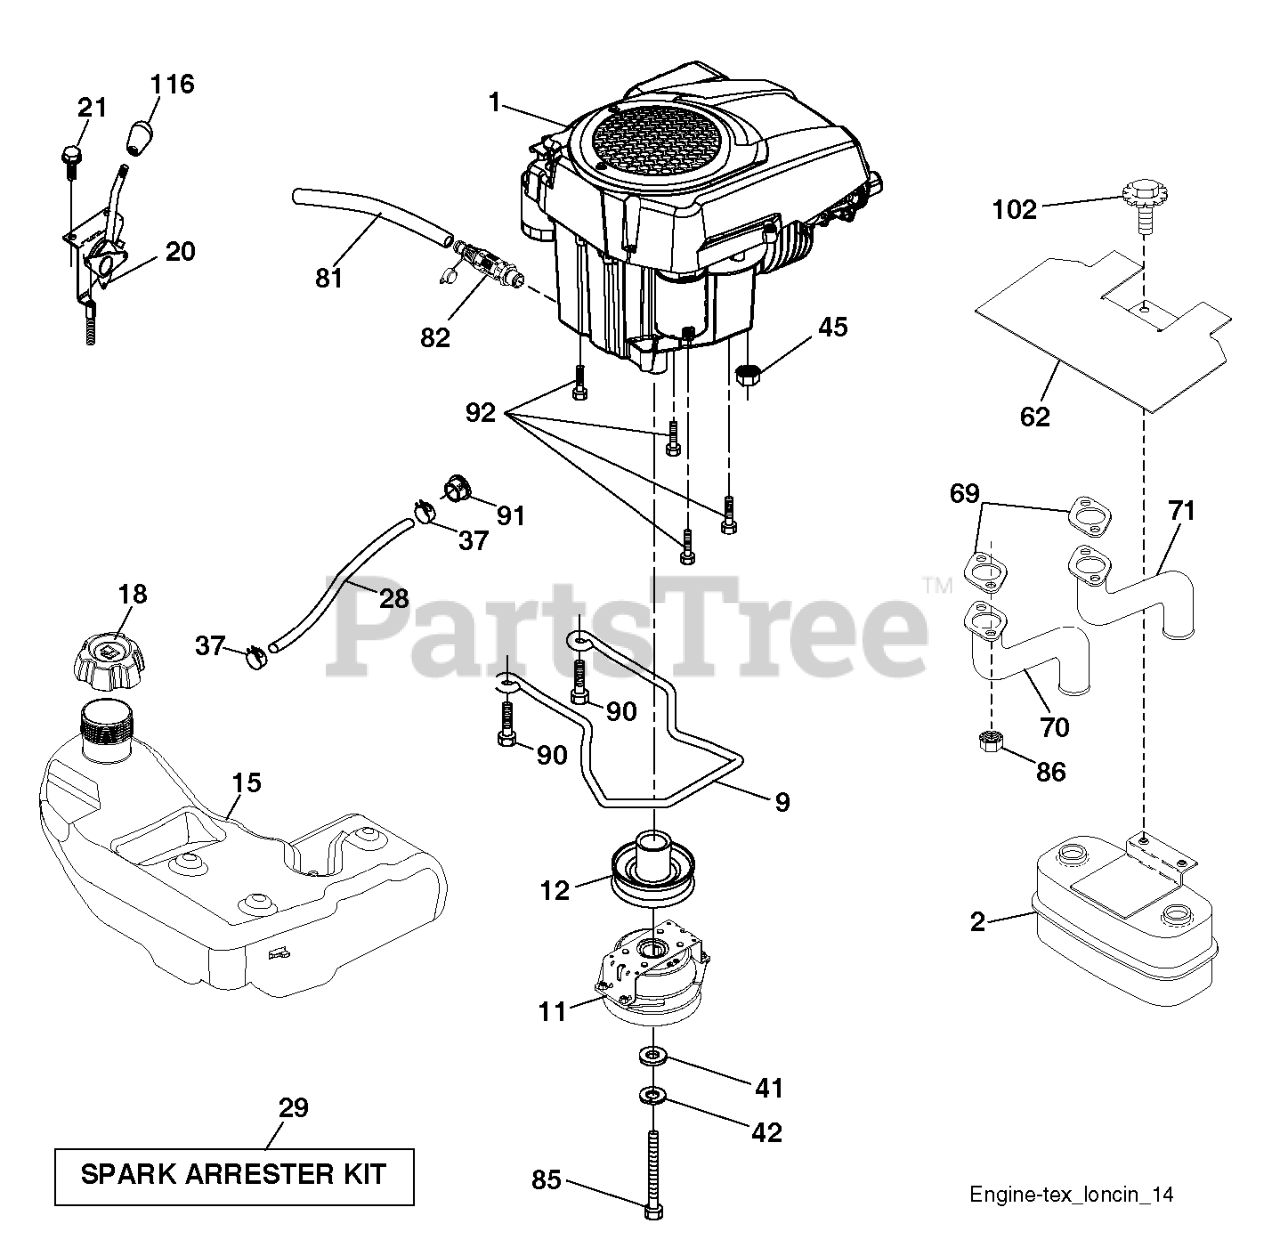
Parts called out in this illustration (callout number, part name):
2	MUFFLER.ASM.TWIN.MNTG.BRACKET
11	CLUTCH.OGURA.5.0PD.GT1.5A-EH01
12	PULLEY ENGINE
15	TANK.FUEL.4GAL
18	CAP.ASSY.FUEL.3".N-EPA.GRY.498
20	CONTROL.THROTTLE/CHOKE.PRO.45
28	LINE.FUEL.64"REAR.EMIS
29	KIT.SPARK ARRESTOR 794945 B&S
37	HOSE CLAMP
45	NUT HEXAGON WITH FLANGE, SERRA
62	SHIELD.HEAT.MUFFLER
81	TUBE, DRAIN OIL ASM.
82	VALUE.OIL.DRAIN
85	BOLT.HEX.7/16-20X3.GR5.YELLOW
86	NUT.HEX.FLANGE.TOPLOCK
90	SCREW 3/8-16X1
91	BUSHING.1.375OD
92	SCREW 3/8-16X1
102	SCREW
116	KNOB - SHIFT
